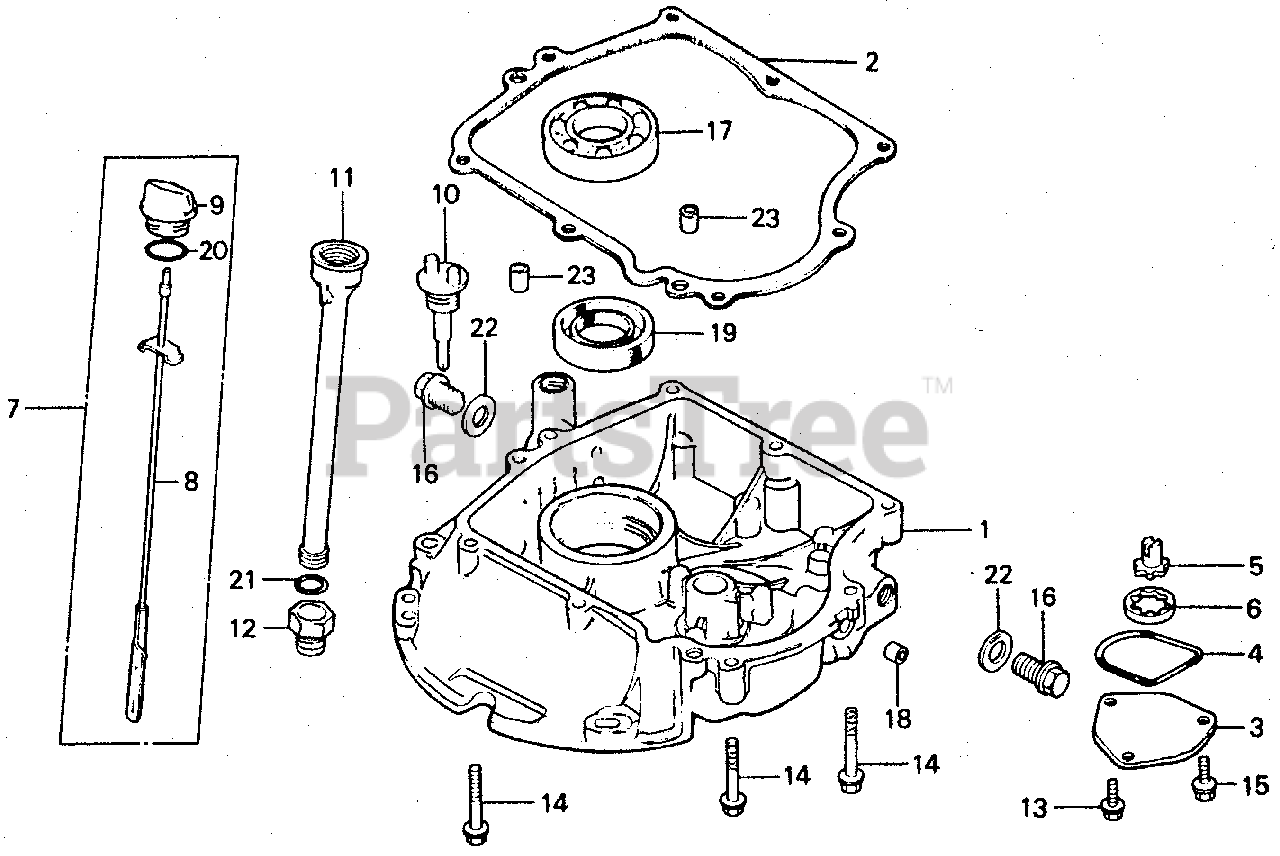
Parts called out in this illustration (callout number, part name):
1	PAN, OIL
2	GASKET, OIL PAN
3	COVER, OIL PUMP
4	O-RING, COVER
5	ROTOR (INNER)
6	ROTOR, OIL PUMP (OUTER)
7	GAUGE ASSY., LEVEL
7	GAUGE ASSY., OIL LEVEL
8	DIPSTICK, OIL
9	CAP, OIL
10	CAP, OIL FILLER
11	PIPE, OIL FILLER
12	BOLT, JOINT
13	BOLT, FLANGE (6X12) (CT200)
14	BOLT, FLANGE (6X32)
15	BOLT, FLANGE (6X16)
16	BOLT, DRAIN PLUG
17	BEARING, RADIAL BALL
18	OIL SEAL (6X11X4)
19	OIL SEAL (25.4X40X7)
20	O-RING (26X2.7)
21	O-RING (15X2.5)
22	WASHER, DRAIN PLUG (12MM)
23	PIN A, DOWEL (8X14)
